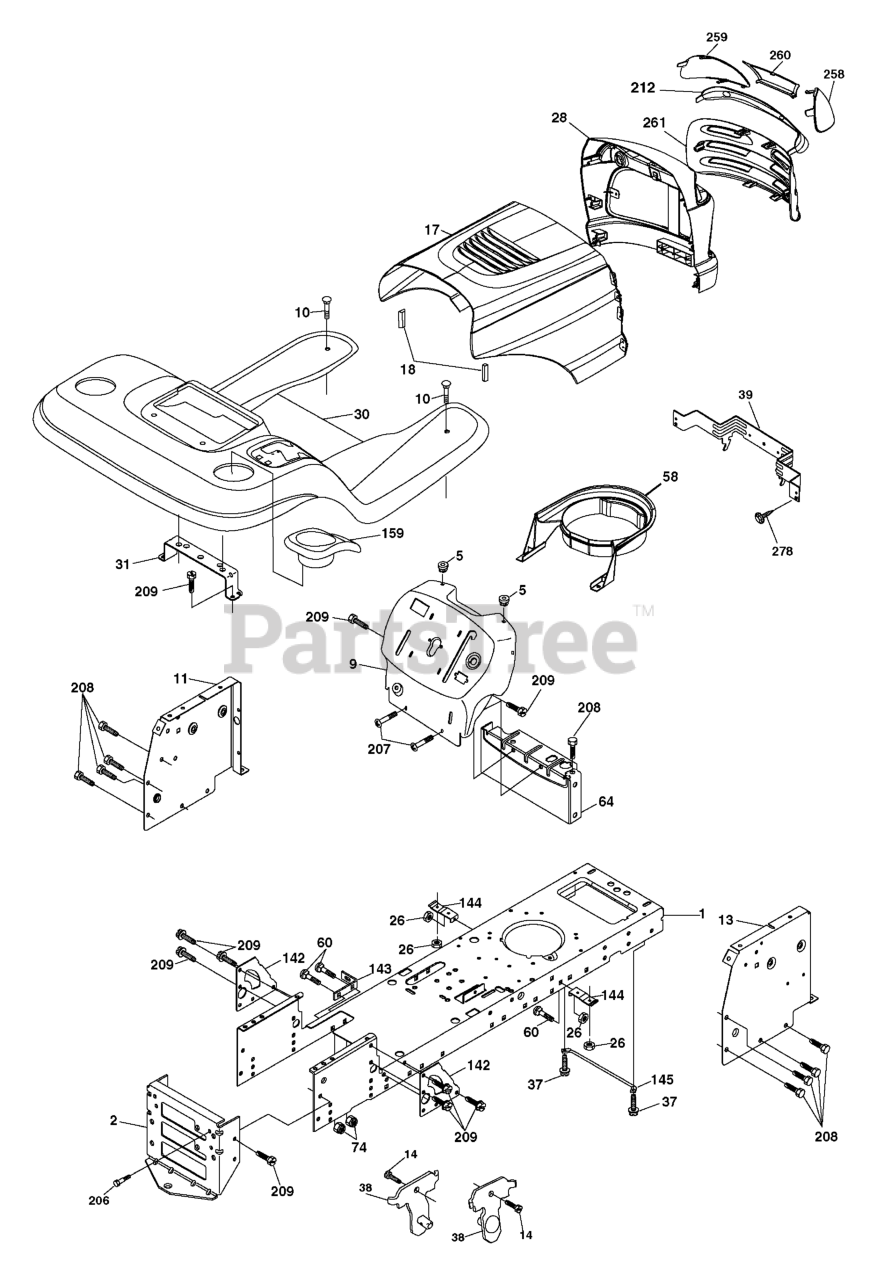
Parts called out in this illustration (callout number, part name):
1	CHASSIS STAMPING
2	DRAWBAR, 12GA
5	BUMPER.RUBBER.HOOD
9	DASH
10	BOLT D
11	PANEL.DASH.LH.LTX
13	PANEL DASH RH
14	SCREW LT
17	HOOD
18	BUMPER.HOOD.LARGE.1.75"
26	NUT
28	GRILL/LEN.ASM.DL.HUSQ
30	FEND/FTREST.STL.W/CPH
31	BRACKET.SUPPORT.FENDER
37	Screw Thdrol 6/16-18 x 1/2 TYT
38	BRACKET.ASM.PIVOT.MOWER.REAR
39	BRACKET PIVOT LASER
60	Bolt RDHD Sqnk 3/8-16 unc x 3/4
64	DASH LOWER
142	PLATE REINFORCEMENT
143	BRACKET, SWAYBAR CHASSIS
144	BRKT, FOOT REST
145	ROD PIVOT CHASSIS/HOOD
159	CUPHOLDER
206	SHOULDER BOLT 5/16-18TT
207	SCREW, 5/16-18 X 1/2
208	Screw Thdrl 3/8-16 x 1/2
209	SCREW, 3/8-16X3/4
212	INSERT.LENS.REFLECTIVE
258	LENS LH
259	LENS LH
260	COVER.LENS.HUSQ.( HAVE GRAY)
261	INSERT GRILLE
278	SCREW
